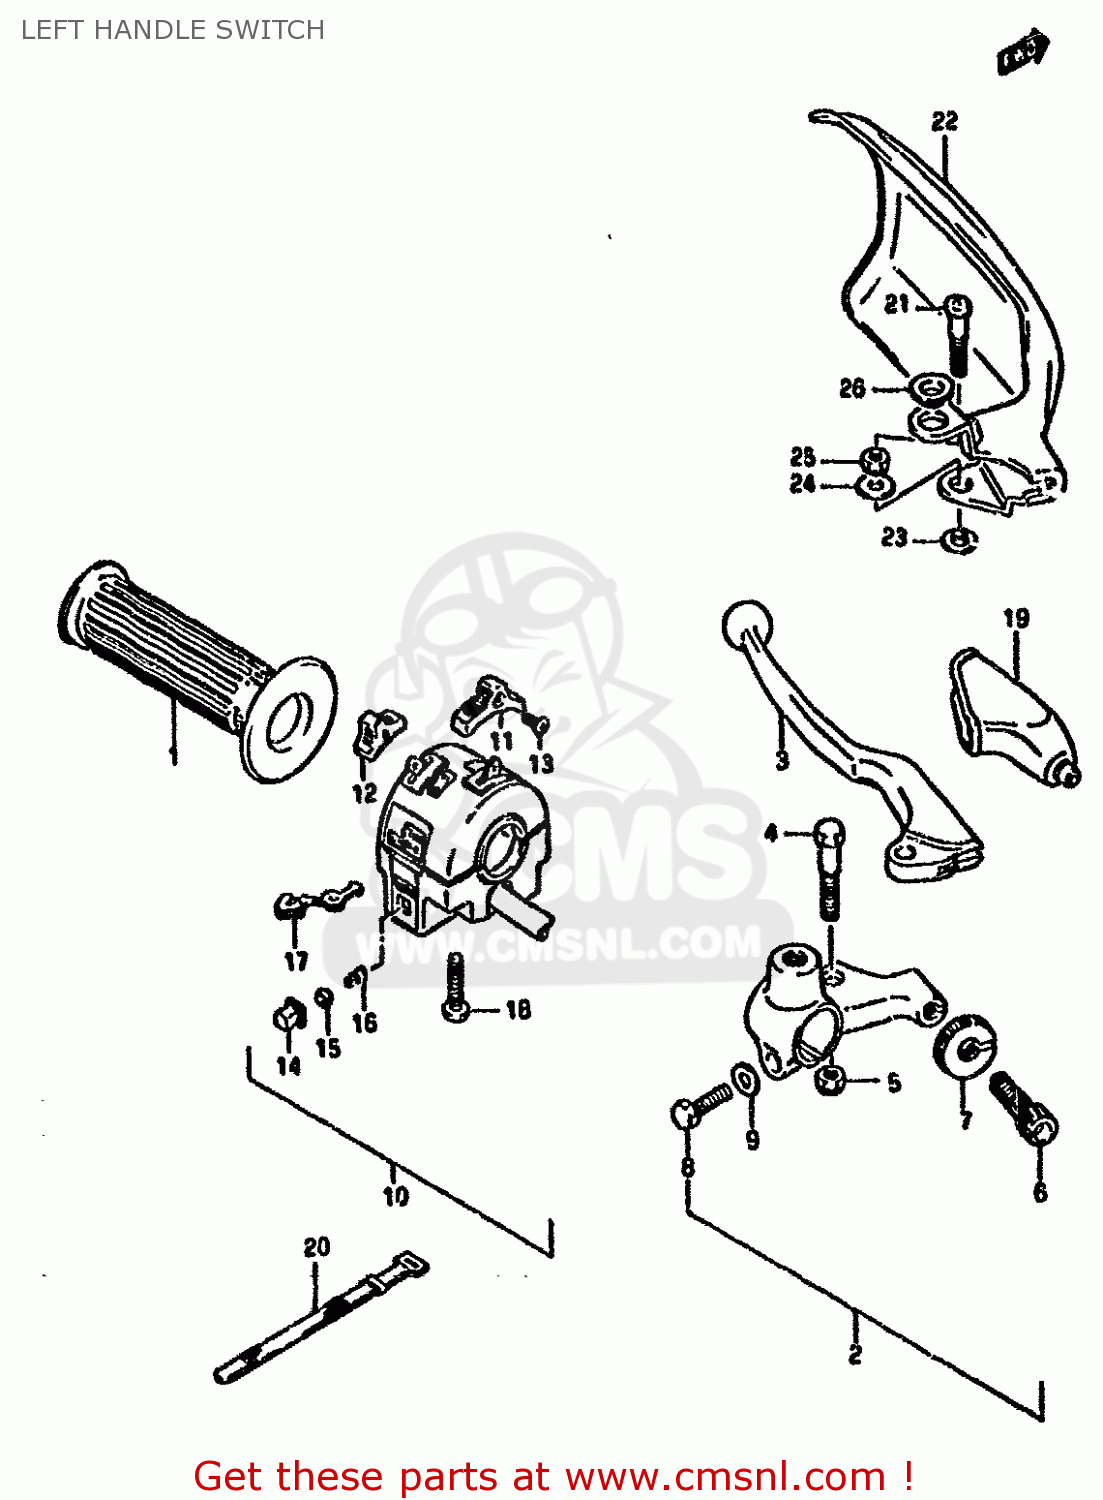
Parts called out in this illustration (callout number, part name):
1	GRIP,L
2	LEVER ASSEMBLY,CLUTCH
3	LEVER,CLUTCH
4	BOLT,LEVER PIVOT
5	NUT
6	ADJUSTER,CABLE
7	NUT,CABLE ADJUSTER LOCK
8	BOLT
9	WASHER
10	SWITCH ASSY,HANDLE LH
11	KNOB,LIGHTING SWITCH
12	KNOB,DIMMER SWITCH
13	SCREW
14	BUTTON,HORN
15	CONTACT
16	SPRING
17	KNOB,TURNSIGNAL
18	SCREW
19	COVER,CLUTCH LEVER
20	CLAMP(L:120)
21	BOLT,LEVER PIVOT
22	COVER,KNUCKLE,L
23	WASHER
24	WASHER(6.5X16X1.2)
25	NUT 6MM
26	WASHER
